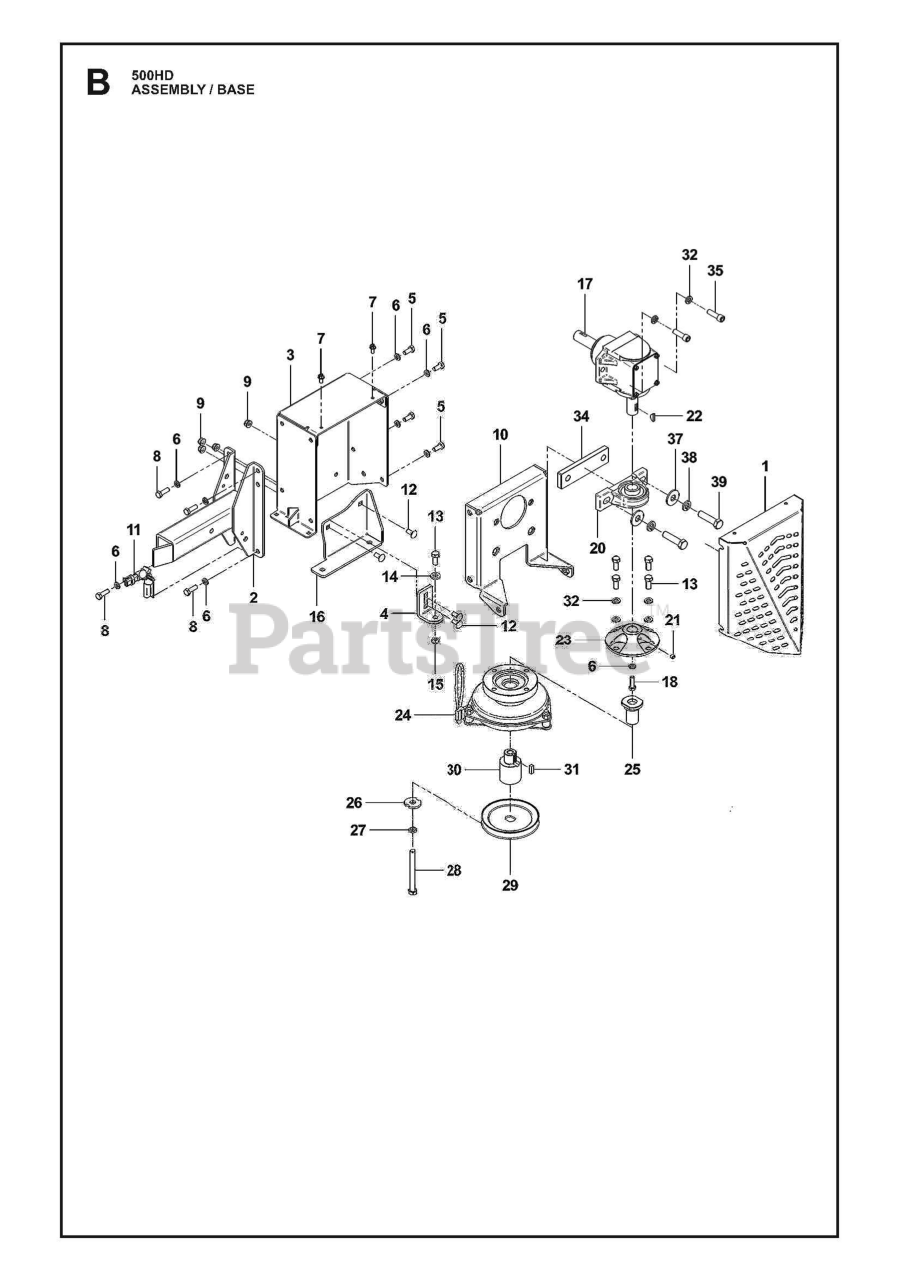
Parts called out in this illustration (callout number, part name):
1	GUARDS
2	ARMS
3	HOUSINGS
4	BRACKETS
5	SCREW HEXAGON HEAD SCREW 5/16-
6	WASHER SPRING LOCK WASHER WITH
7	SCREW
8	Bolts
9	NUT HEXAGON FLANGE 5/16-18 ST
10	BRACKETS
11	HARNESSES
12	GSPW Bolts
13	BOLTS
14	GSPW Washers
15	NUTS
16	PLATES
17	GEARBOX
18	BOLTS
20	BEARINGS
21	SCREWS
22	KEYS
23	FLANGE
24	CLUTCHES
25	SHAFTS
26	WASHERS
27	Washers
28	BOLT.HEX.7/16-20X4.GR5.1.5BLUE
29	PULLEYS
30	BUSHINGS
31	KEYS
32	Washers
34	SPACERS
35	BOLTS
37	Washers
38	WASHER 1/2" SPLIT LOCK
39	BOLTS
